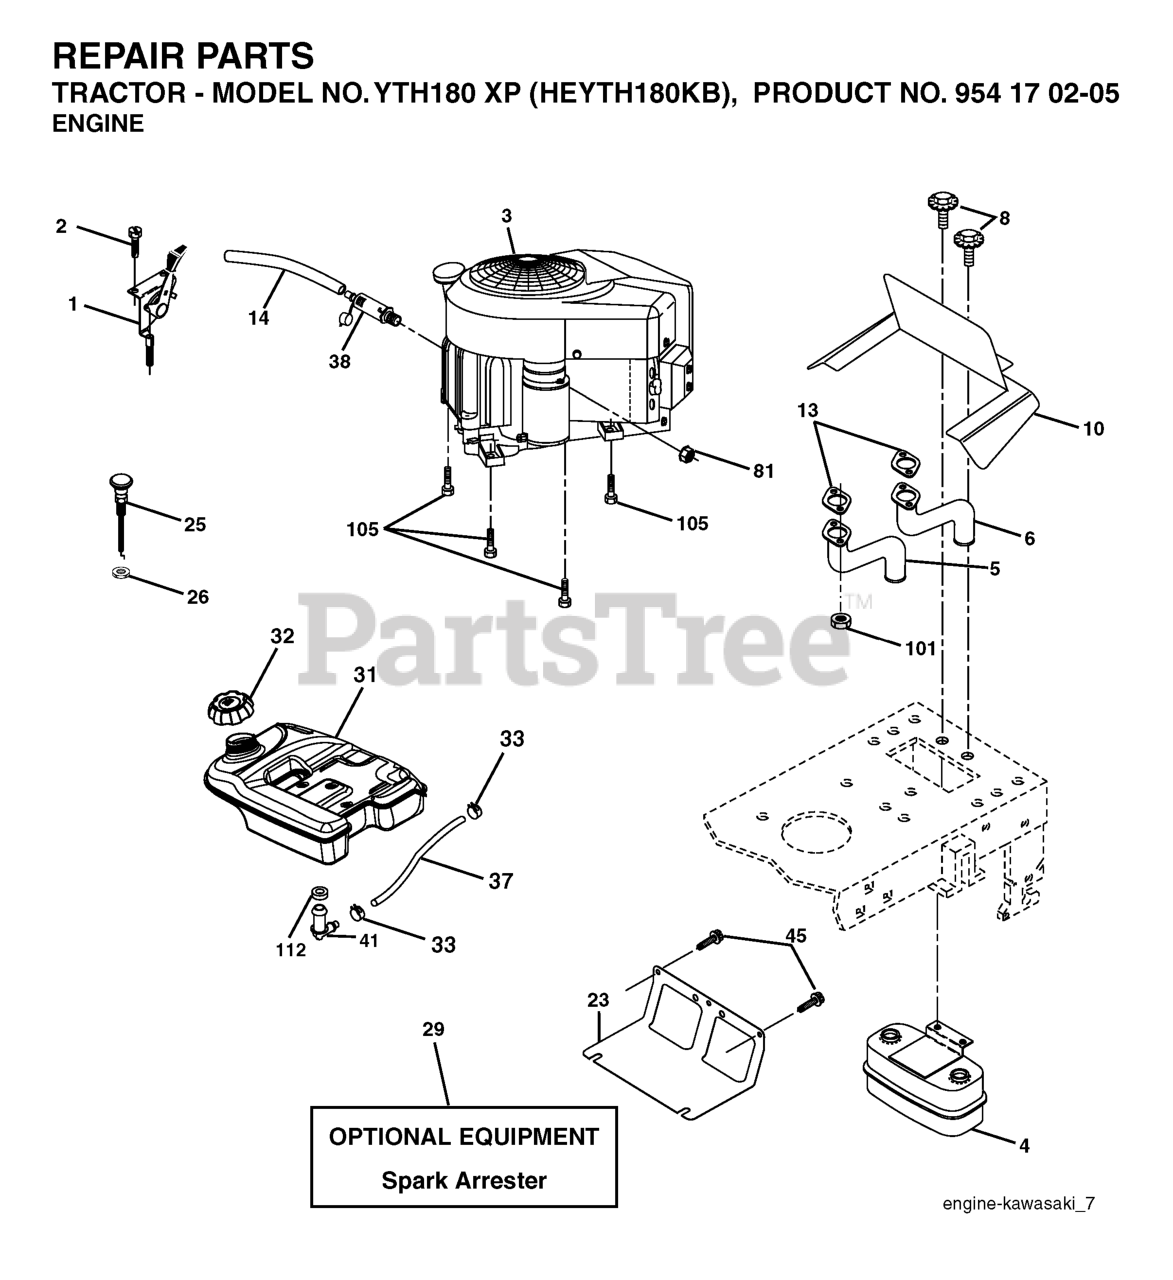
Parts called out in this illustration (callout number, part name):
1	CONTROL, THROTTLE
2	SCREW
4	MUFFLER.TWIN.CYL.LOW.TONE
5	EXHAUST.TUBE.LH.KAWASAKI.
6	EXHAUST.TUBE.RH.KAWASAKI.
8	BOLT.5/16-18UNCX3/4 W/SEMS.BLK
10	RP SHIELD HEAT MUFFLER
14	TUBE, DRAIN OIL ASM.
23	SHIELD.BROWNING.DBR.GUARD
25	CHOKE CONTROL
26	Nut Keps 3/8 - 24 UNF
29	KIT.SPARK ARRESTOR 794945 B&S
31	4.0 REAR FUEL TANK
32	TANK CAP
33	HOSE CLAMP
37	REPL BY 532 00 85-43
41	STEM FUEL TANK
45	SCREW, 3/8-16X3/4
81	NUT
101	NUT.HEX.FLANGE.TOPLOCK
105	SCREW 3/8-16X1
112	BUSHING OUTLET T
